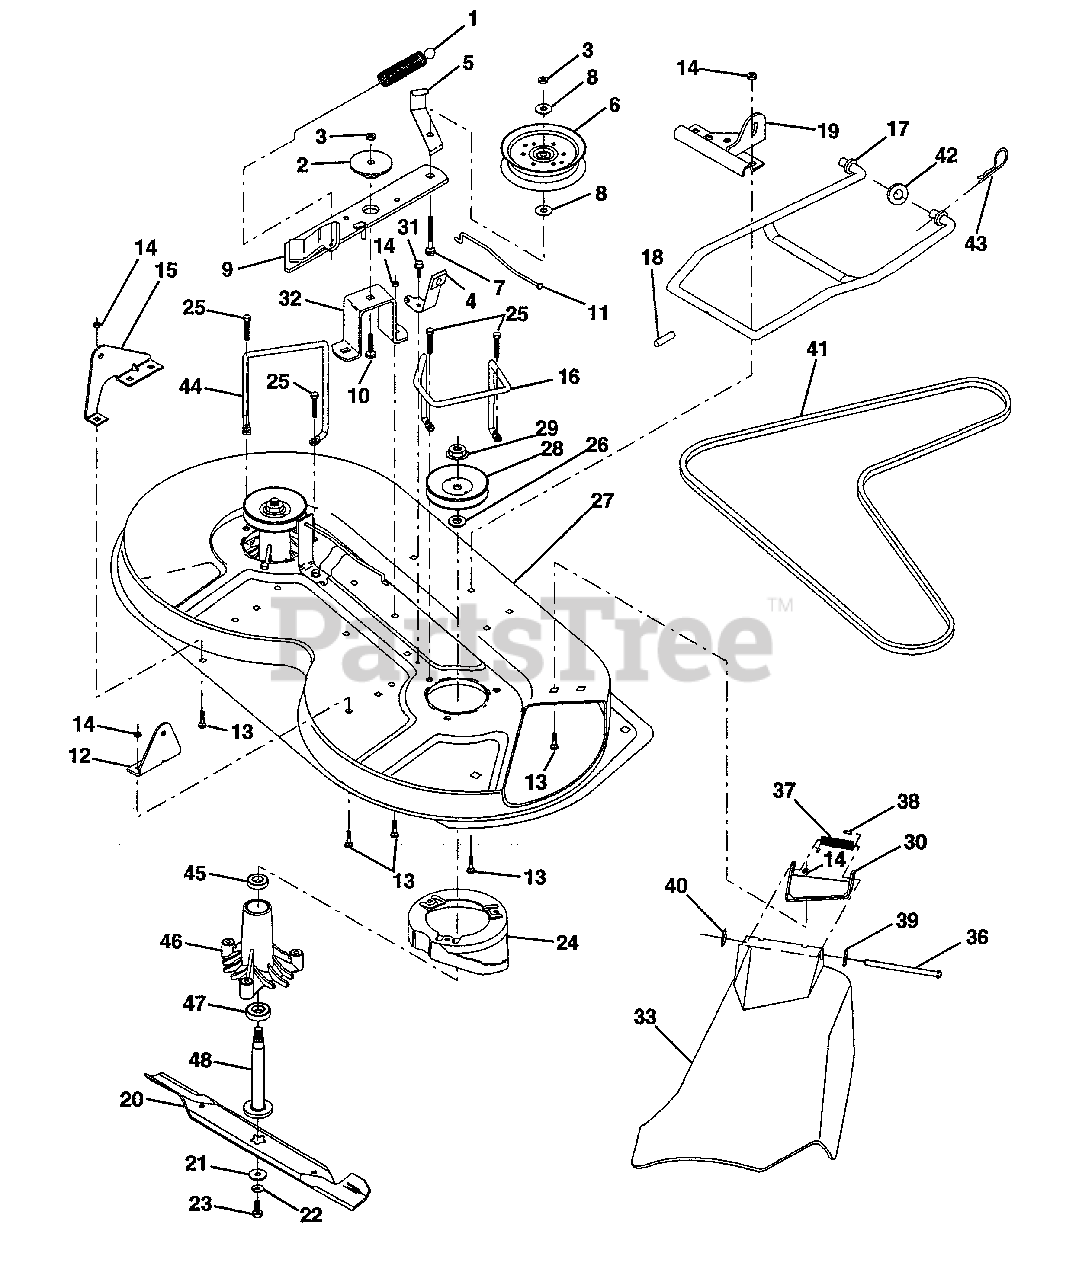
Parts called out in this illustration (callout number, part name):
1	Spring, Mower Clutch
2	Spacer, Retainer
3	Nut, Crownlock
4	Brake Asm.
5	Guide, Belt Idler
6	Pulley, Flat Idler
7	Bolt, Carr. 3/8-16 x 2 Gr. 5
8	Washer 13/21 x 7/8 x 10 Ga.
9	Arm Asm., Idler Mower
10	Bolt, Carriage 3/8-16 x 1
11	Rod, Brake
12	Bracket, Lift R. H. Rear
13	Bolt, Carriage 5/16-18 x 5/8
14	Nut, Crownlock 5/16-18
15	Bracket, Lift L. H. Rear
16	Keeper, R. H.
17	Link, Asm. Mower Stabilizer
18	Pin, Drive
19	Bracket, Asm. Front
20	Blade
21	Washer, Hard
22	Washer, Lock 3/8
23	Bolt 3/8-24 x 1-1/4 Gr. 8
24	Stripper
25	Bolt 5/16-18 x 1-1 /4
26	Washer .150 Thk.
27	Deck Assembly
28	Pulley, Mandrel
29	Nut, Flangelock 9/16
30	Bracket, Asm. Deflector
31	Screw, Hex Wsh. Thdrol. 5/16-18 x 1/2
32	Arm, Support Idler Mower
33	Deflector
36	Rod, Hinge
37	Spring, Torsion Deflector
38	Cap, Sleeve
39	Washer 11/32 x 5/8 x 16 Ga.
42	Washer 11/32 x 5/8 16 Ga.
43	Retainer, Spring
44	Keeper, L. H.
46	Mandrel Asm.
48	Shaft, Mandrel
